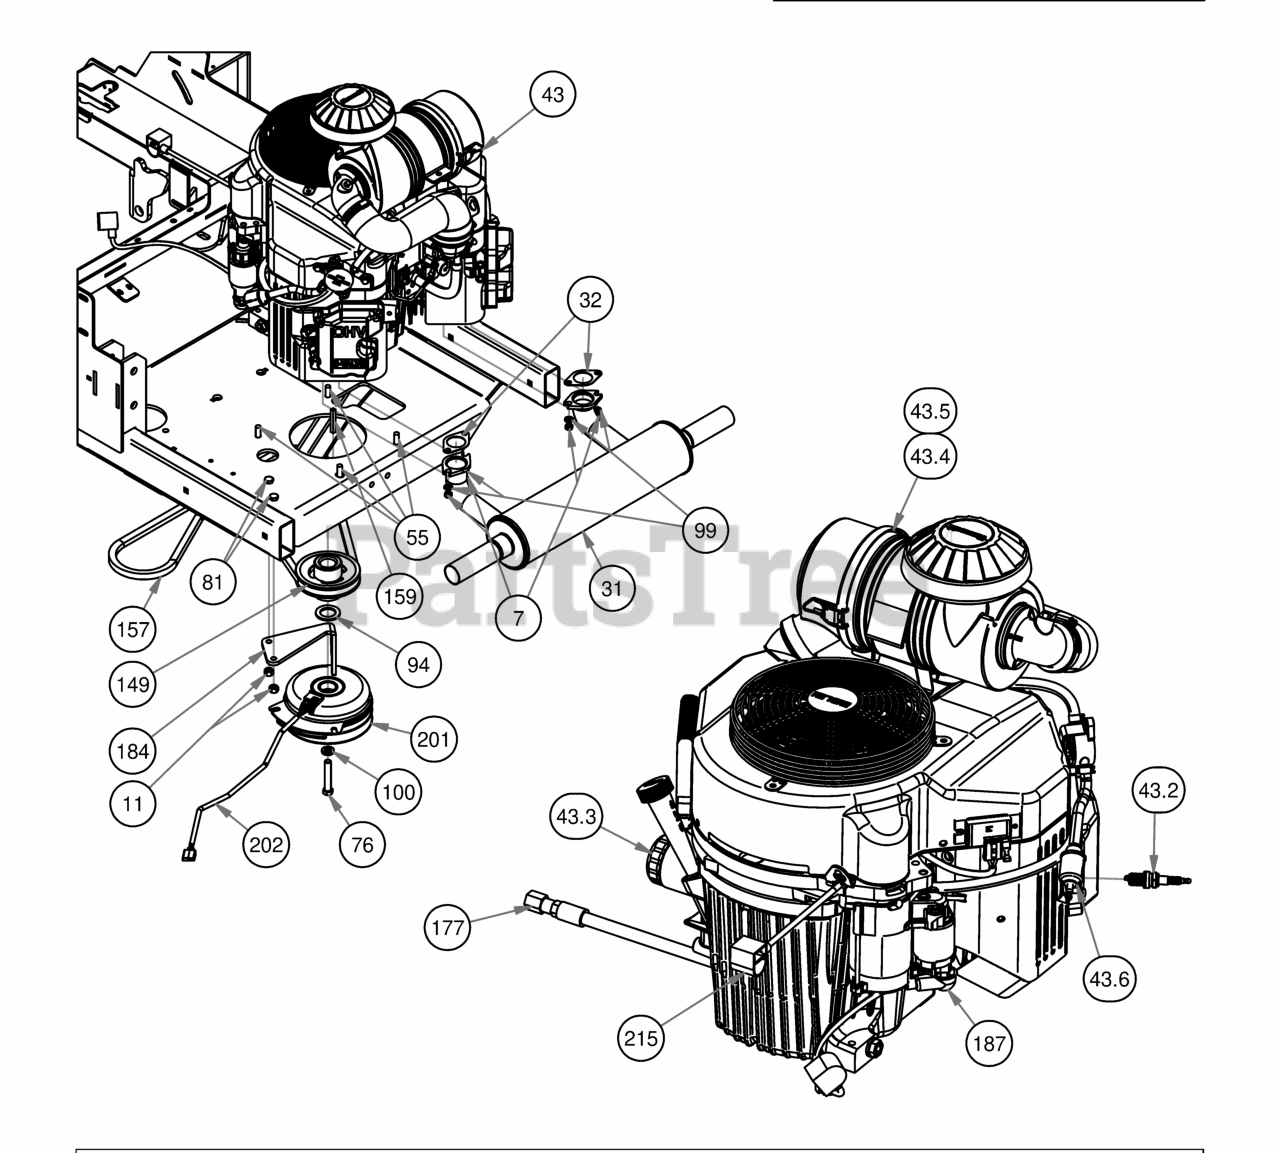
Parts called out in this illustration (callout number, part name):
7	M8-1.25 Zinc Nut
11	3/8" Hex Nut
31	Muffler for Kawasaki FX1000
32	Exhaust Gasket
43	Kawasaki FX1000 Engine
43.2	Spark Plug - Kawasaki
43.3	Oil Filter
43.4	Canister Air Filter- Inner
43.5	Canister Air Filter- Outer
43.6	Universal Inline Fuel Filter
55	3/8 x 1 1/8 bolt
76	7/16" x 2 1/2" Hex Bolt
81	3/8" x 1" Hex Bolt
94	1 1/8" Flat Spacer
99	5/16" Lock Washer
100	7/16" Lock Washer
149	4 3/4 Motor Pulley
157	2019 Rogue Pump Belt 68"
159	1/4 x 2 Square key Stock
177	Kawasaki Oil Drain
184	PTO Engager Holder
187	24" Red Battery Cable
201	Clutch Assembly
202	Clutch Pigtail
203	2019 Veritical Suspension Frame
215	Starter Cable
217	Kawasaki Harness Adapter
